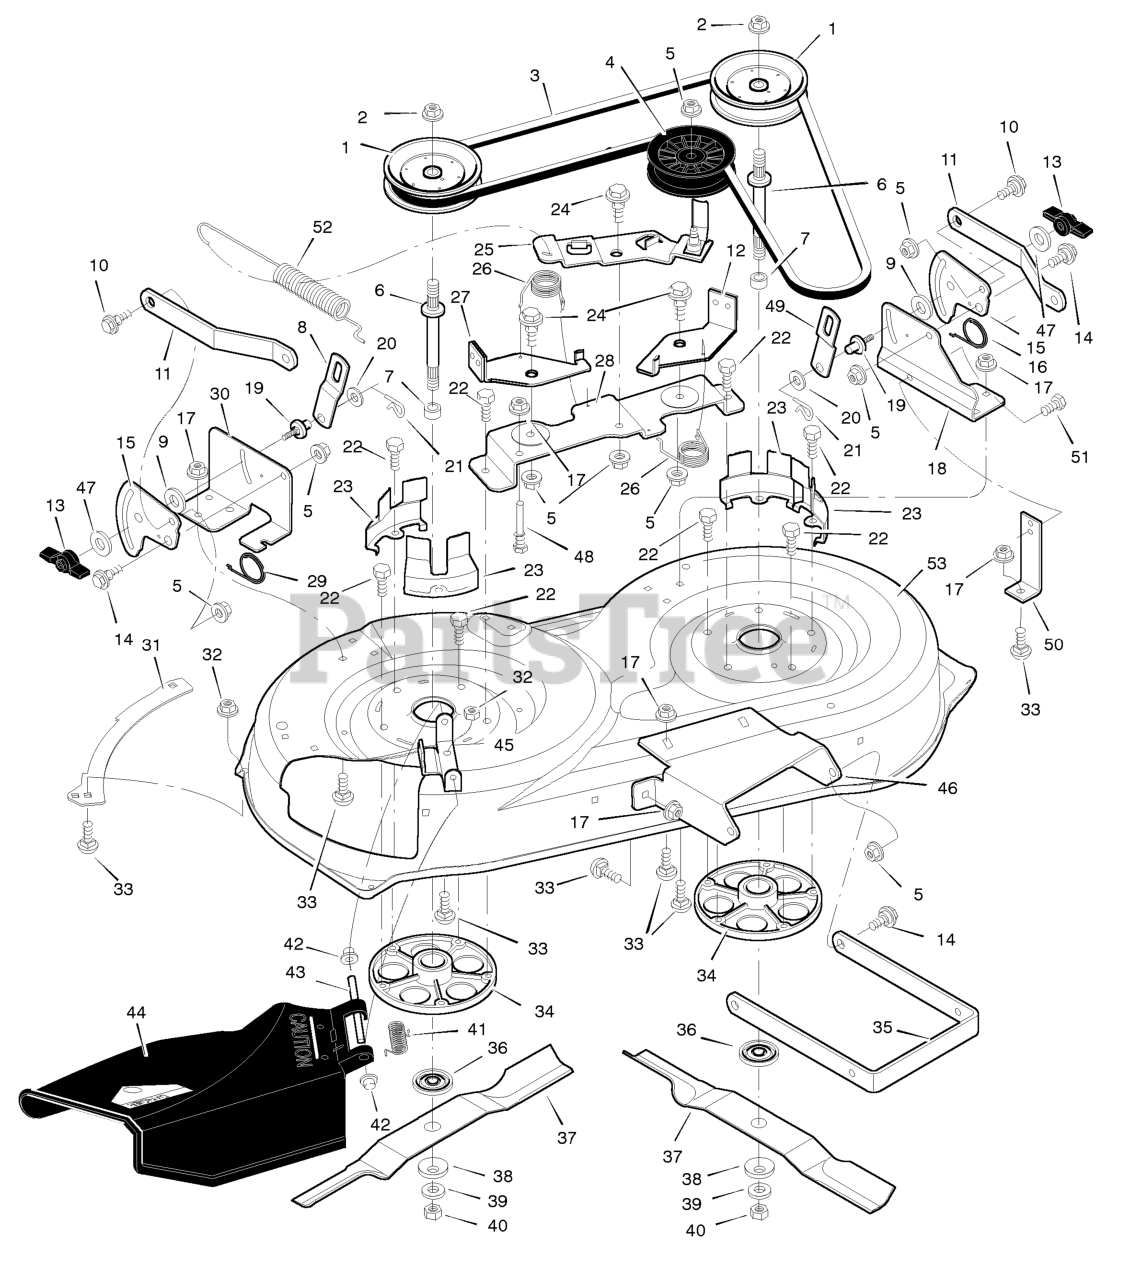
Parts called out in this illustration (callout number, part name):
1	Pulley, Jackshaft
2	Nut, Hex
3	Belt, Mower Drive
4	Pulley, Idler
5	Nut, Flange
6	Jackshaft
8	Link, Right Lift
9	Pad, Friction
10	Bolt, Shoulder
11	Bracket, Suspension
12	Pad Assembly, Left Brake
13	Knob
14	Bolt, Shoulder
15	Plate, Suspension
17	Nut, Flange
18	Bracket, Suspension
19	Pin, Hanger
21	Pin, Cotter
22	Bolt
23	Cover, Pulley
24	Bolt, Shoulder
25	Arm, Idler
27	Pad Assembly, Right Brake
28	Bracket Assembly, Brake
30	Bracket, Suspension
31	Plate
32	Nut, Flange
33	Bolt, Carriage
34	Mandrell
35	Bracket, Suspension
36	Adapter, Blade
42	Cap, Push On
43	ROD, Deflector
44	Deflector
45	Bracket, Deflector
46	Bracket, Front Hanger
48	Guide, Belt
49	Link, Left Lift
50	Bracket, Support
52	Spring, Extension
53	Housing, Blade
